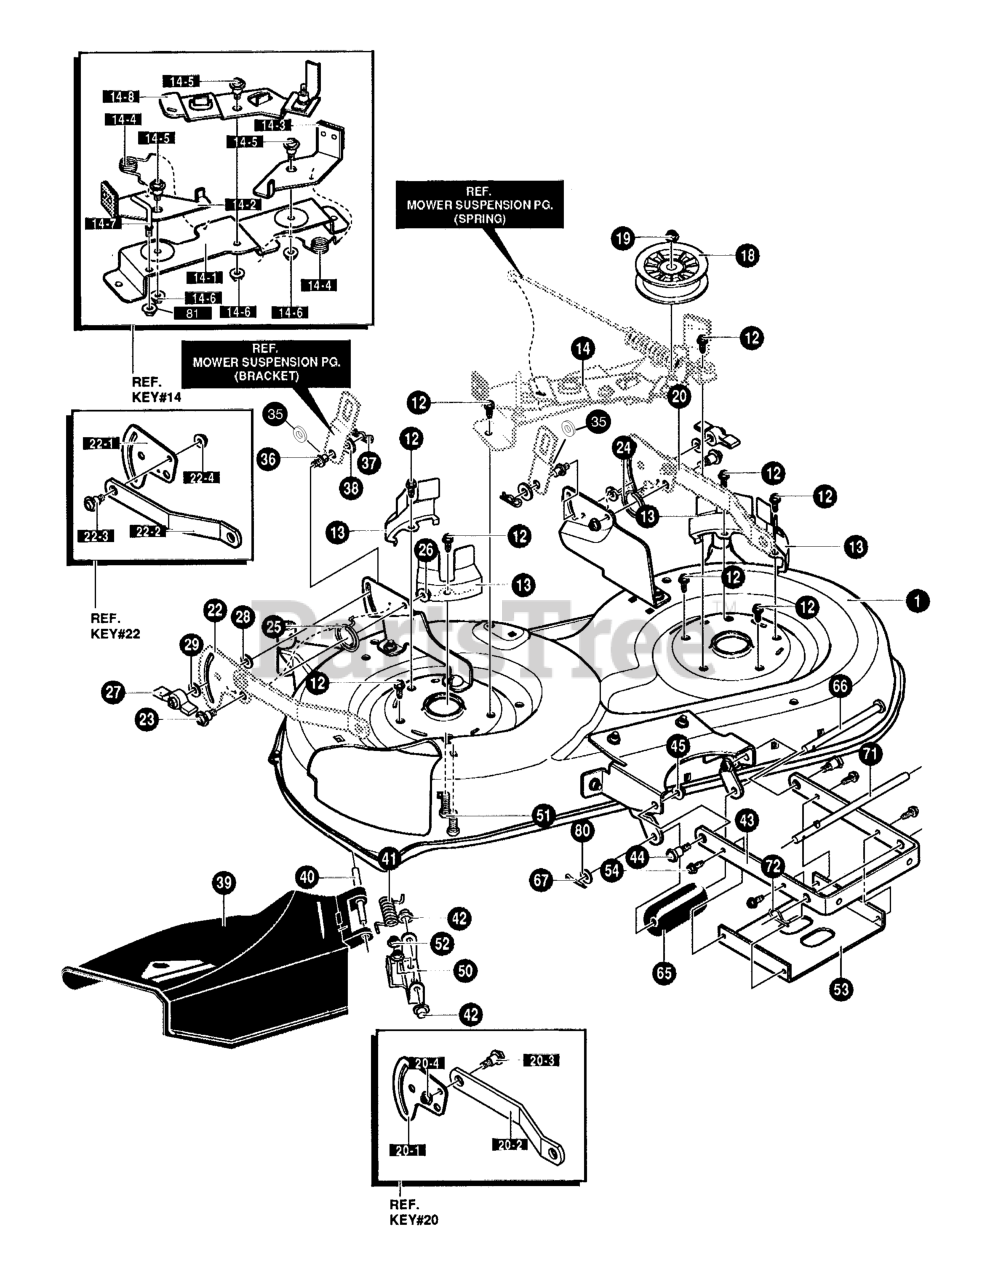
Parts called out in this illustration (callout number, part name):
1	ASSY 42" MOWER DECK
12	SCREW, 3/8- 1 6X1 .25
13	COVER, SEGMENT BELT GUIDE
14-1	BRACKET, BRAKE MT
14-2	ASSY BRAKE RH
14-3	ASSY BRAKE RH
14-4	TORSION SPRING
14-5	BOLT.50X.75
14-6	NUT, 3/8- 16
14-7	SCREW GUIDE
14-8	ASSY IDLER ARM
18	PULLEY, IDLER
19	NUT, 3/8- 16
20	PLATE, REAR SUS. BRKT. LH
20-1	PLATE - SUSPENSION
20-2	SUSPENSION BRKT REAR
20-3	BOLT, SHOULDER 3/8- 16
20-4	NUT, 3/8- 16
22	PLATE, REAR SUS. BRKT. RH
22-1	PLATE - SUSPENSION
22-2	SUSPENSION BRKT REAR
22-3	BOLT, SHOULDER 3/8- 16
22-4	NUT, 3/8- 16
23	BOLT, SHOULDER
24	SPRING, TORSION
25	SPRING, TORSION
26	NUT, 3/8- 16
28	PAD, FRICTION
35	WASHER, WAVE
36	PIN, HANGER
37	PIN, HAIR
38	WASHER, FLAT
39	CHUTE DEFLECTOR
40	ROD, CHUTE DEFLECTOR
41	SPRING, TORSION
42	NUT, PUSH CAP
43	BRACKET, FRT SUSPENSION
44	BOLT, SHOULDER
45	NUT, 3/8- 16
50	BRACKET, CHUTE
51	BOLT, 5/16- 18X.63
52	NUT, 5/16- 18
53	STIFFENER NLT
54	SCREW, 5/16-18 x 0.75
66	ROD, SUPPORT
67	PIN, COTTER
71	ROD HANGER
72	HAIR PIN
80	FLATWASHER
81	NUT, HEX
